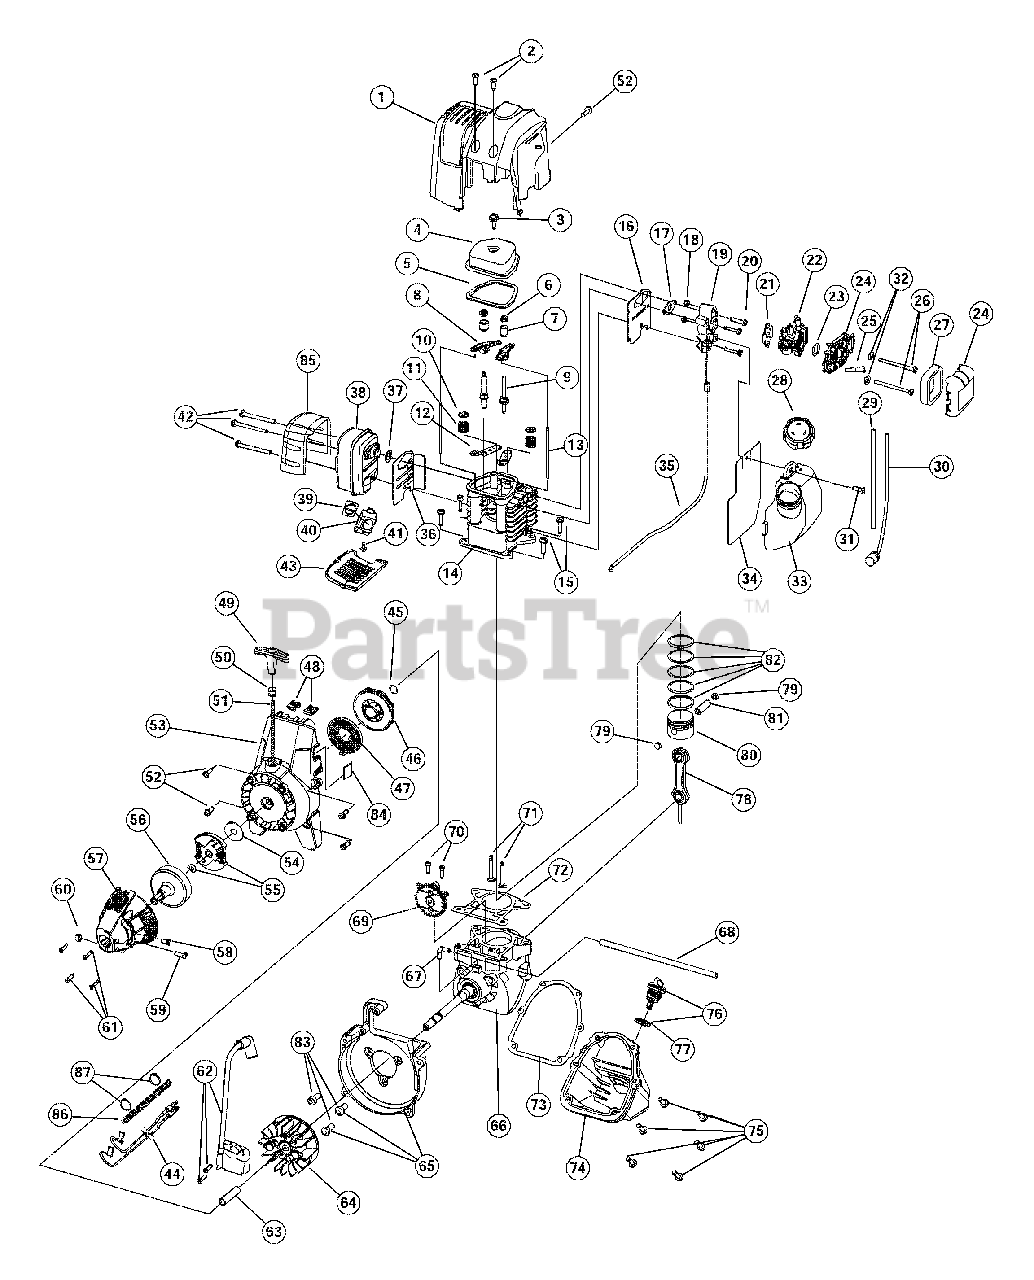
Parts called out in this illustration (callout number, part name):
1	Engine Cover
2	Engine Cover Screws
3	Valve Cover Screw
4	Valve Cover
5	Valve Cover Gasket
6	Rocker Adjustment Nut
7	Rocker Arm Pivot
9	Rocker Arm Stud
10	Valve Spring Retainer
11	Valve Spring
12	Push Rod Guide
14	Cylinder Assembly (includes 9, 15, 71 & 72)
15	Cylinder Screw
16	Intake Baffle
17	Carburetor Mount Gasket
18	Nut
19	Carburetor Mount (includes 18)
20	Carburetor Mount Screw
21	Carburetor Gasket
22	Carburetor with Primer
23	O-Ring, Carburetor
24	Air Filter/Choke Cover Assembly includes 27)
25	Breather Tube
26	Air Filter Mounting Screw
29	Fuel Return Line
30	Fuel Pick-Up Line with Filter
31	Screw
33	Fuel Tank Assembly (includes 28-30)
34	Fuel Tank Shield
35	Throttle Cable
36	Muffler Baffle
37	Muffler Gasket
38	Muffler (includes 37, 39-41)
39	Spark Arrestor Screen
40	Screen Cover
42	Muffler Mounting Screw
43	Muffler Cover
44	Switch Wire Assembly
46	Recoil Pulley
47	Recoil Spring
49	Pull Handle
52	Starter Housing Screw
53	Starter Housing Assembly (includes 45-52)
54	Clutch Washer
55	Clutch w/Spacer
56	Clutch Drum
57	Clutch Cover
58	Anti-Rotation Screw
61	Clutch Cover Screw
62	Ignition Module with Screws
65	Shroud Assembly (includes 83)
66	Crankcase Assembly (includes 67 & 68)
68	Breather Hose
69	Cam Bracket Assembly
70	Cam Bracket Screw
71	Valves. Intake and Exhaust
72	Cylinder Gasket
73	Oil Pan Gasket
74	Oil Pan (includes 75 & 77)
75	Oil Pan Screw
76	Dipstick Assembly (Includes 77)
78	Connecting Rod
79	Wrist Pin Button
80	Piston (includes 82)
82	Piston Ring Set
83	Shroud Screw
85	Heat Sheild
86	Wire Cover
87	Cable Clamp
